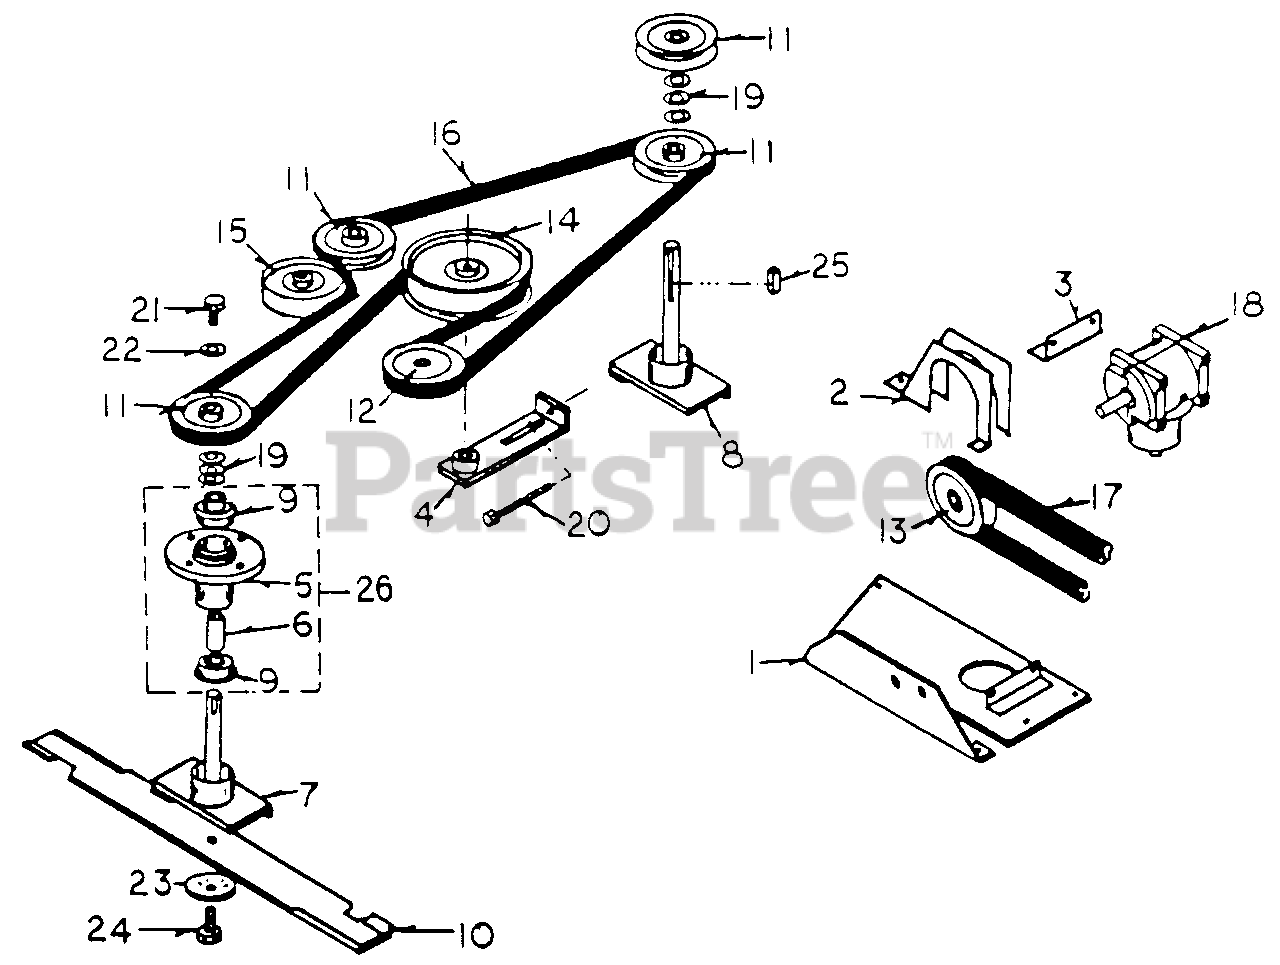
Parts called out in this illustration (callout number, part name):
2	Belt Guard
3	Gearbox Mount Angle
4	Belt Tightener
5	Spindle Housing
6	Spindle Spacer
7	Spindle Shafe
8	Spindle Shaft, Long
9	Spindle Bearing
11	Spindle Pulley
12	Cearbox Pulley, Output
13	Gearbox Pulley, Input
14	Idler Pulley, Large
15	Idler Pulley, Small
17	Deck Drlve Belt
20	Adjustment Bolt
21	Hex Ny-Lock Bolt, 5/16-24 x 3/4"
22	Washer, 5/16", 10GA
24	Hex Bole, 3/8-24 x 1 1/4"
25	Key Stock, 3/16"
26	Spindle Housing Assemly
